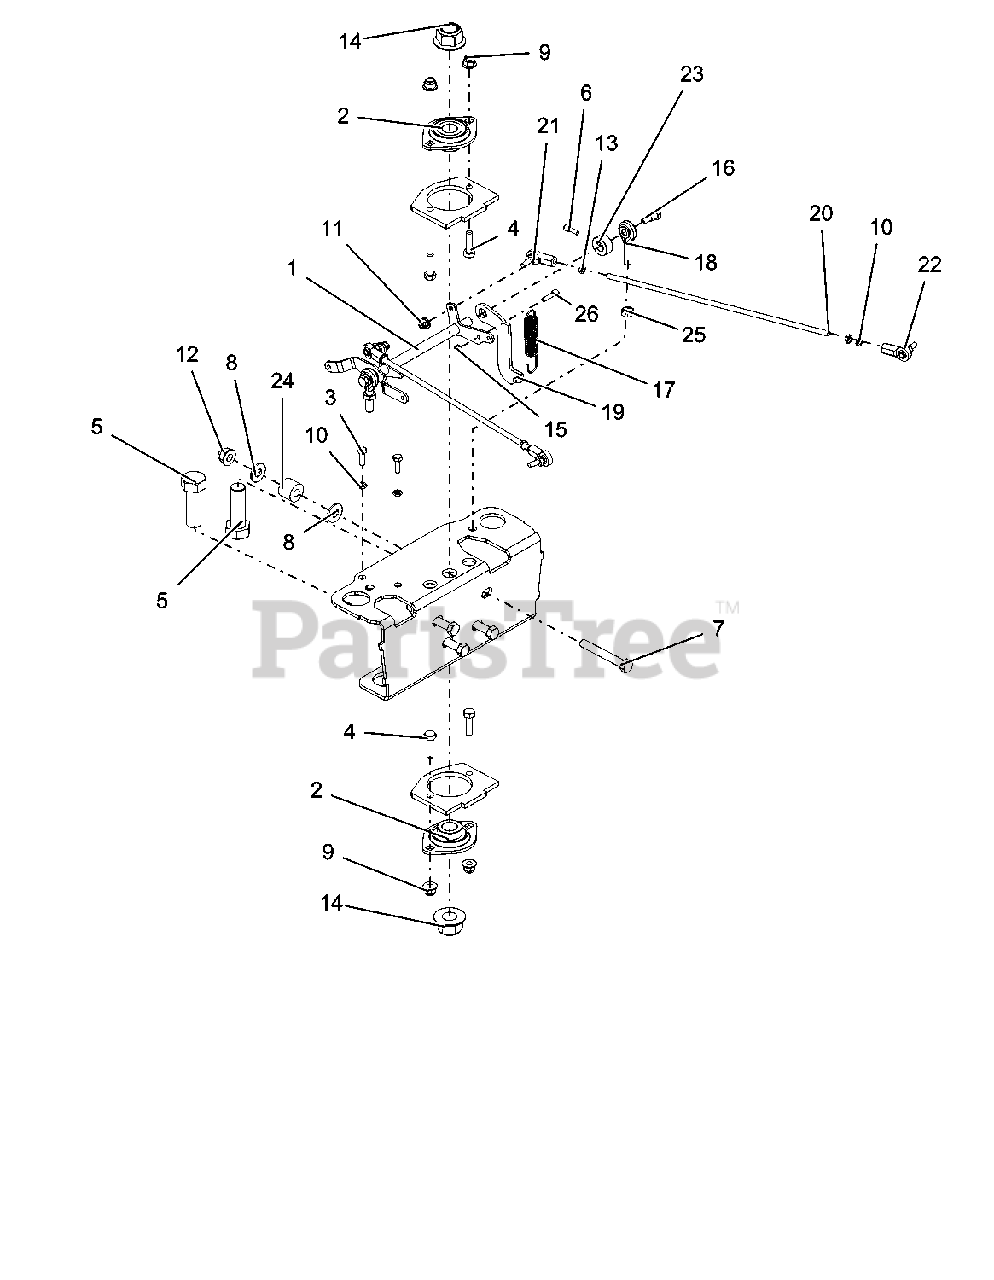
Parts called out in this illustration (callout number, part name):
1	WLDMT, ARM DRIVE-RED
2	BEARING, 2 BOLT FLANGE - .75 ID
3	BLT, HEX M6-1X20 GR8.8 ZC120
4	BLT, HEX M8-1.25X30 GR8.8 CKF
5	BLT, HEX 0.75-10X2.25 GR5 ZC120
6	SCR, SKH M5-.8 X 16 GR12.9 ROHS
7	BLT, HEX M10-1.5X75 GR8.8 ZC120
8	WSHR-FL-STL .438X1.00X.083 ZC120
9	NUT, LK-NYL-FLG M8-1.25 GR8.8 ZC120
10	NUT, HEX-JAM M6-1.0 GR8.8 ZC120
11	NUT, LK-NYL-FLG M6-1.0 GR8.8 ZC120
12	NUT, LK-NYL-FLG M10-1.5 GR8.8 ZC120
13	NUT, HEX-JAM M6-1.0LH GR8.8 ZC120
14	NUT, LK-NYL-FLG M12-1.75 GR8.8 ZC120
15	NUT, HEX M5-0.8 GR 8.8 ZC120
16	BOLT, SHLDR -.375 X .375 X .25-20
17	SPRG, EXTENSION .063 X .653 X 2.755
18	ROD, END 3/8 RH REV
19	LATCH, REVERSE-RED
20	ROD, DRIVE THREADED LH-RH
21	LINKAGE, BALL JOINT M6X1.00 LH
22	LINKAGE, BALL JOINT M6X1.0 RH
23	COLLAR, LOCKING REVERSE
24	BUMPER, STEERING
25	NUT, HEX-JAM .375-24 ZC120
26	SCR, SKH M5-.8 X 20 GR12.9 ROHS
